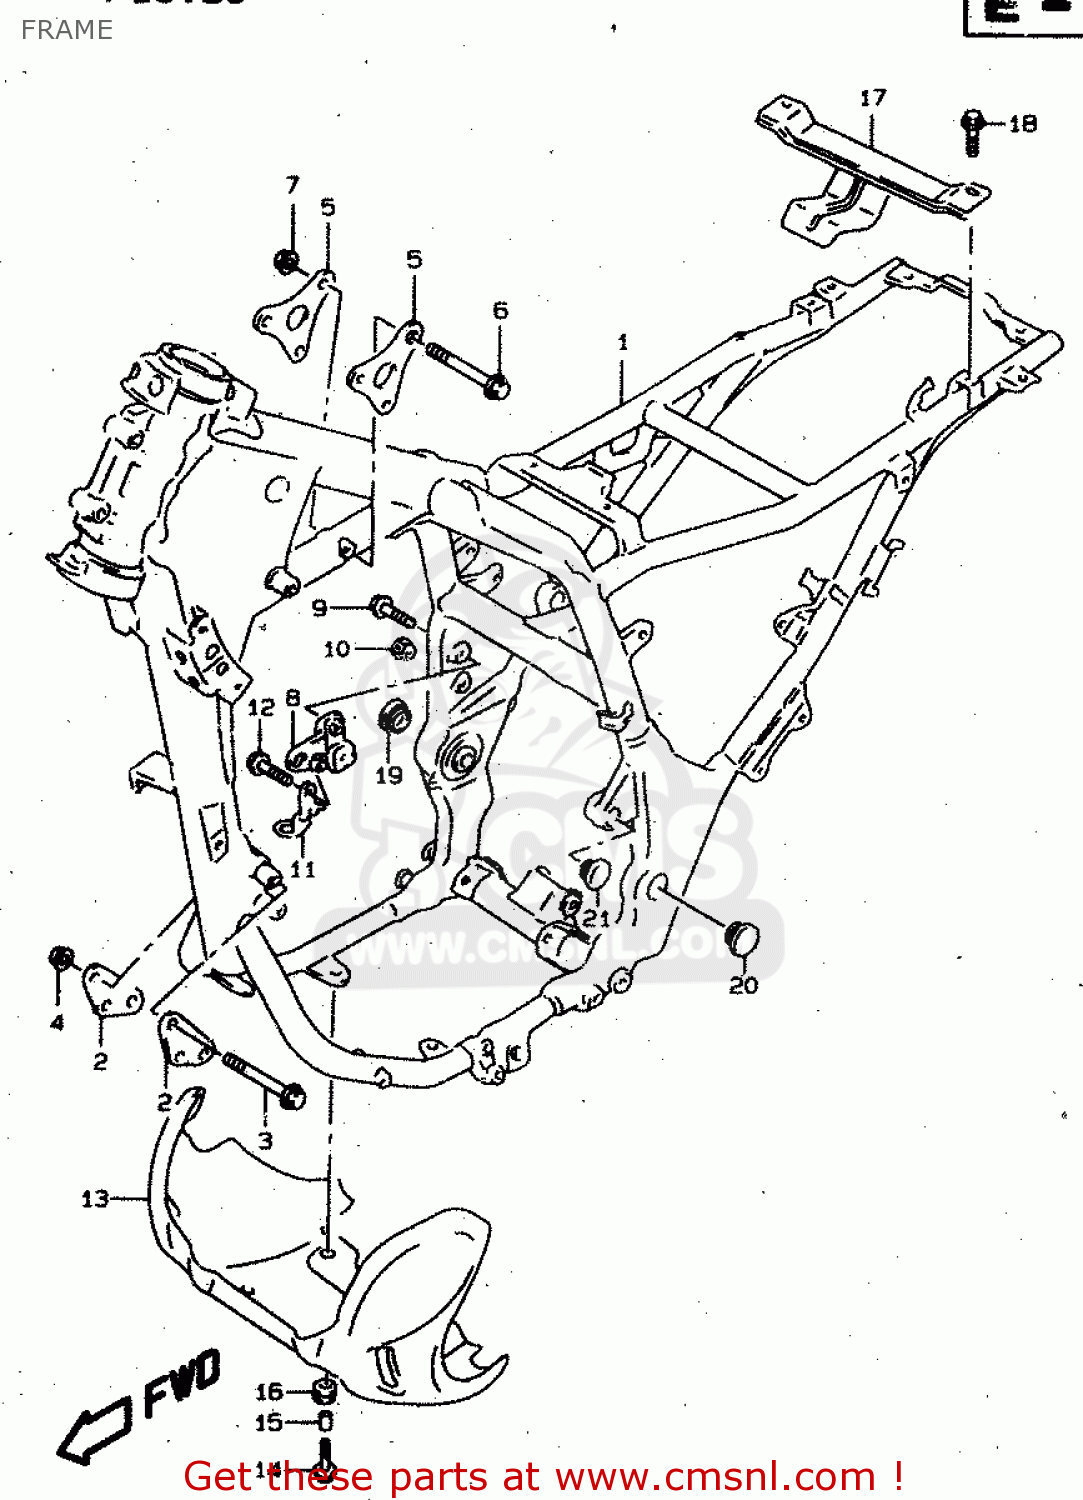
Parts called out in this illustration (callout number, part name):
1	FRAME(CHARCOAL)
2	PLATE,ENG MTG FR
3	BOLT(8X100)
4	NUT
5	PLATE,ENG MTG UPR
6	BOLT
7	NUT
8	PLATE,ENG MTG RR,R
9	BOLT(8X20)
10	PLUG(OD:22)
11	BRACKET,STOP SWITCH
12	SCREW
13	PROTECTOR,ENG.
14	BOLT(6X16)
15	SPACER(6.5X9X7)
16	CUSHION
17	PLATE,BATT FITING
18	BOLT
19	PLUG,FRAME PIVOT,R
20	PLUG,FRAME PIVOT,L
21	PLUG,FRAME BOSS
